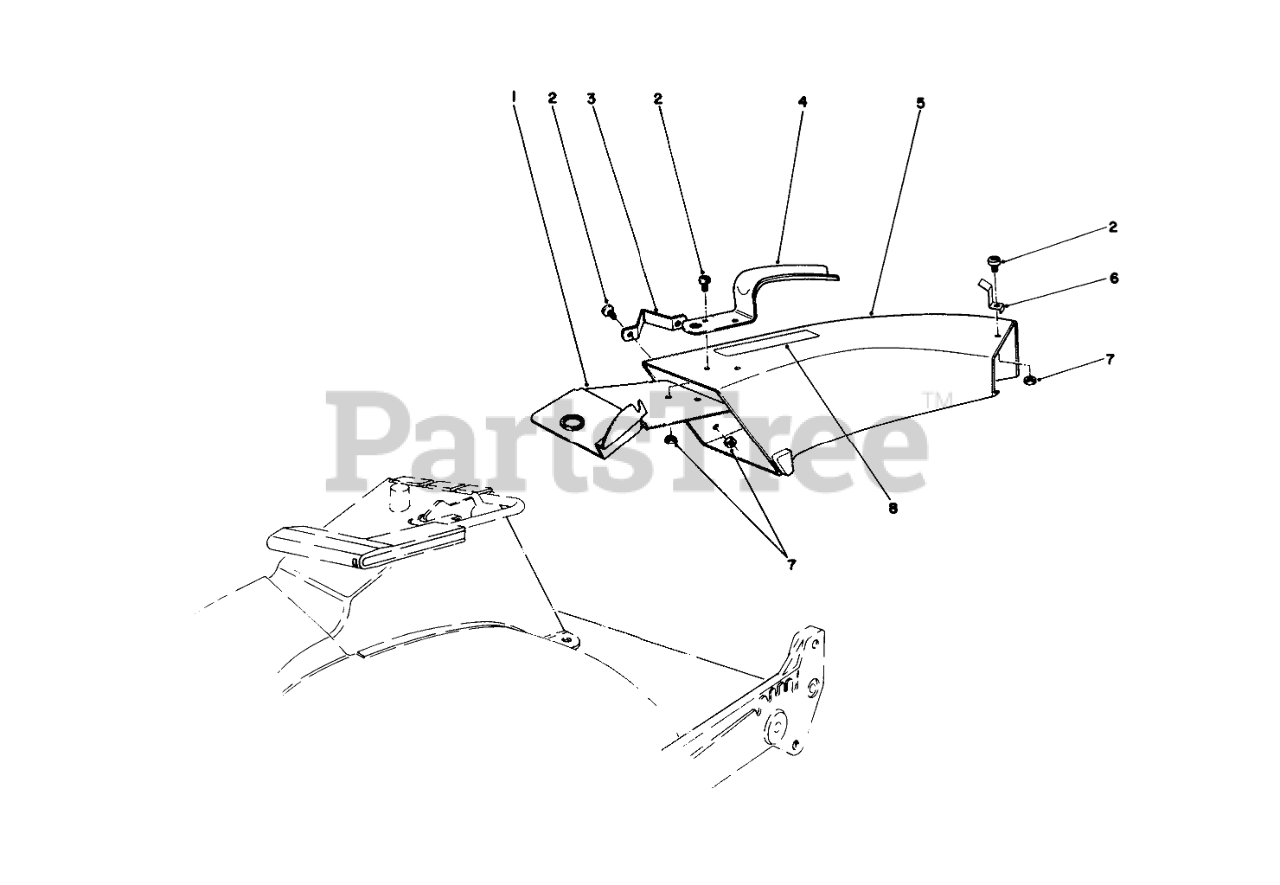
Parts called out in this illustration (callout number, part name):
1	Plate-Discharge Chut
2	10-24 X 5/8 PAN HD MS
3	SIDE BRACKET
4	CHUTE HANDLE
5	Chute-Discharge (Incl. Ref. #8)
7	NUT-LOCK, NI
8	DECAL CAUTION
